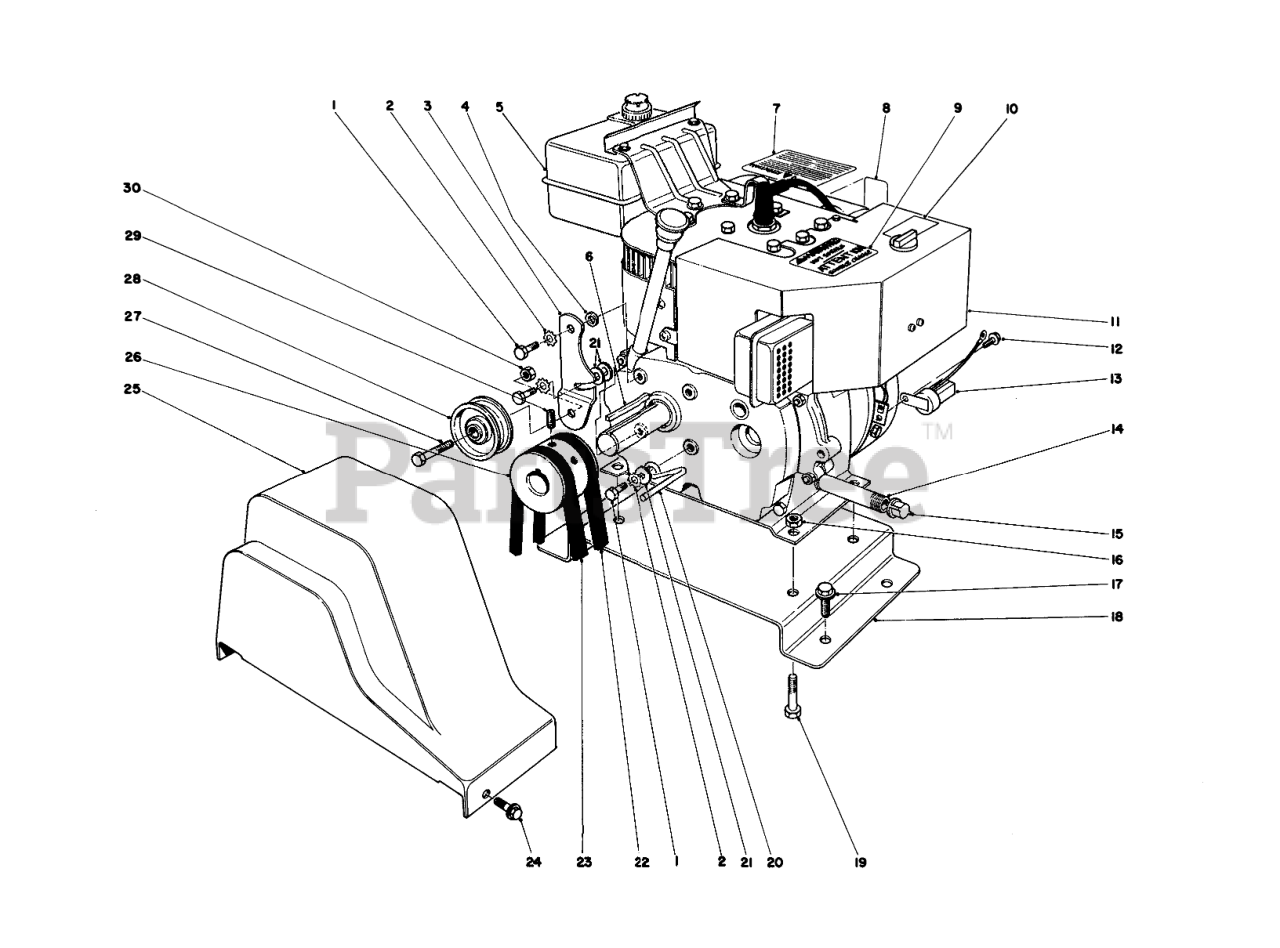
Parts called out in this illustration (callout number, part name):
1	SCREW-HH
2	WASHER-LOCK
3	ENGINE IDLER ARM
4	SPACER
5	Fuel Tank w/Cap (Model 38050)
7	Decal-Hazard
8	PRIMER DECAL
9	Decal Hot Surface Warning
10	CHOKE DECAL
11	Engine (Model 38040)
12	SCREW
13	INTERLOCK MODULE
14	NIPPLE-PIPE
15	CAP-PIPE
16	NUT-LOCK, NI
17	SCREW-HHFTF
18	ENG MTG PLATE R
19	SCREW-HH
20	BELT RETAINER
21	WASHER-PLAIN
22	V-BELT
23	V-BELT
24	SCREW-HWH
25	BELT GUARD
26	ENGINE PULLEY
27	SCREW-HH
28	PULLEY-IDLER
29	Screw-Set
30	NUT-LOCK, NI
